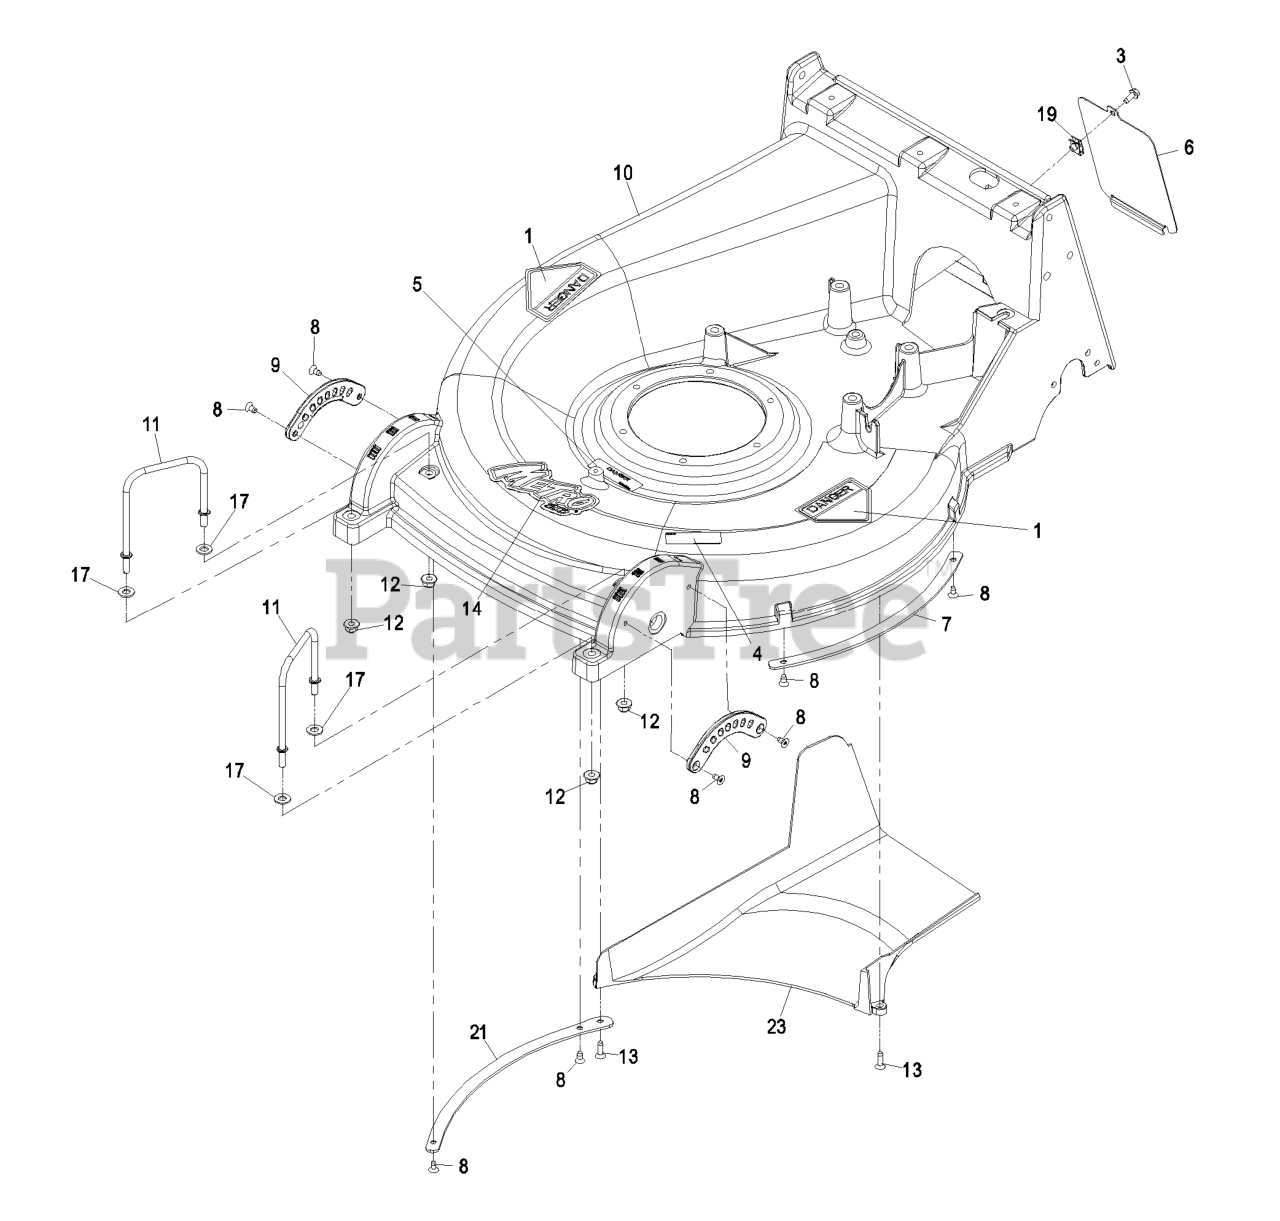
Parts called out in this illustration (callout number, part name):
1	DECAL-DANGER
3	SCREW-HWH
4	DECAL-BLADE
5	DECAL-COVER, MISSING
6	COVER-ACCESS, AXLE
7	PLATE-SKID, 10 GAGE
9	QUADRANT-FRONT
10	ASM,DECK M26 W/DECALS
12	NUT-HF, NI
13	SCREW-TORX
14	DECAL,METRO 26
17	WASHER-FLAT
19	Nut, Retainer-Panel 1/4-20
21	PLATE-SKID
22	BUSHING,SHOULDER
23	PLASTIC CHUTE KIT (W/SCRE
